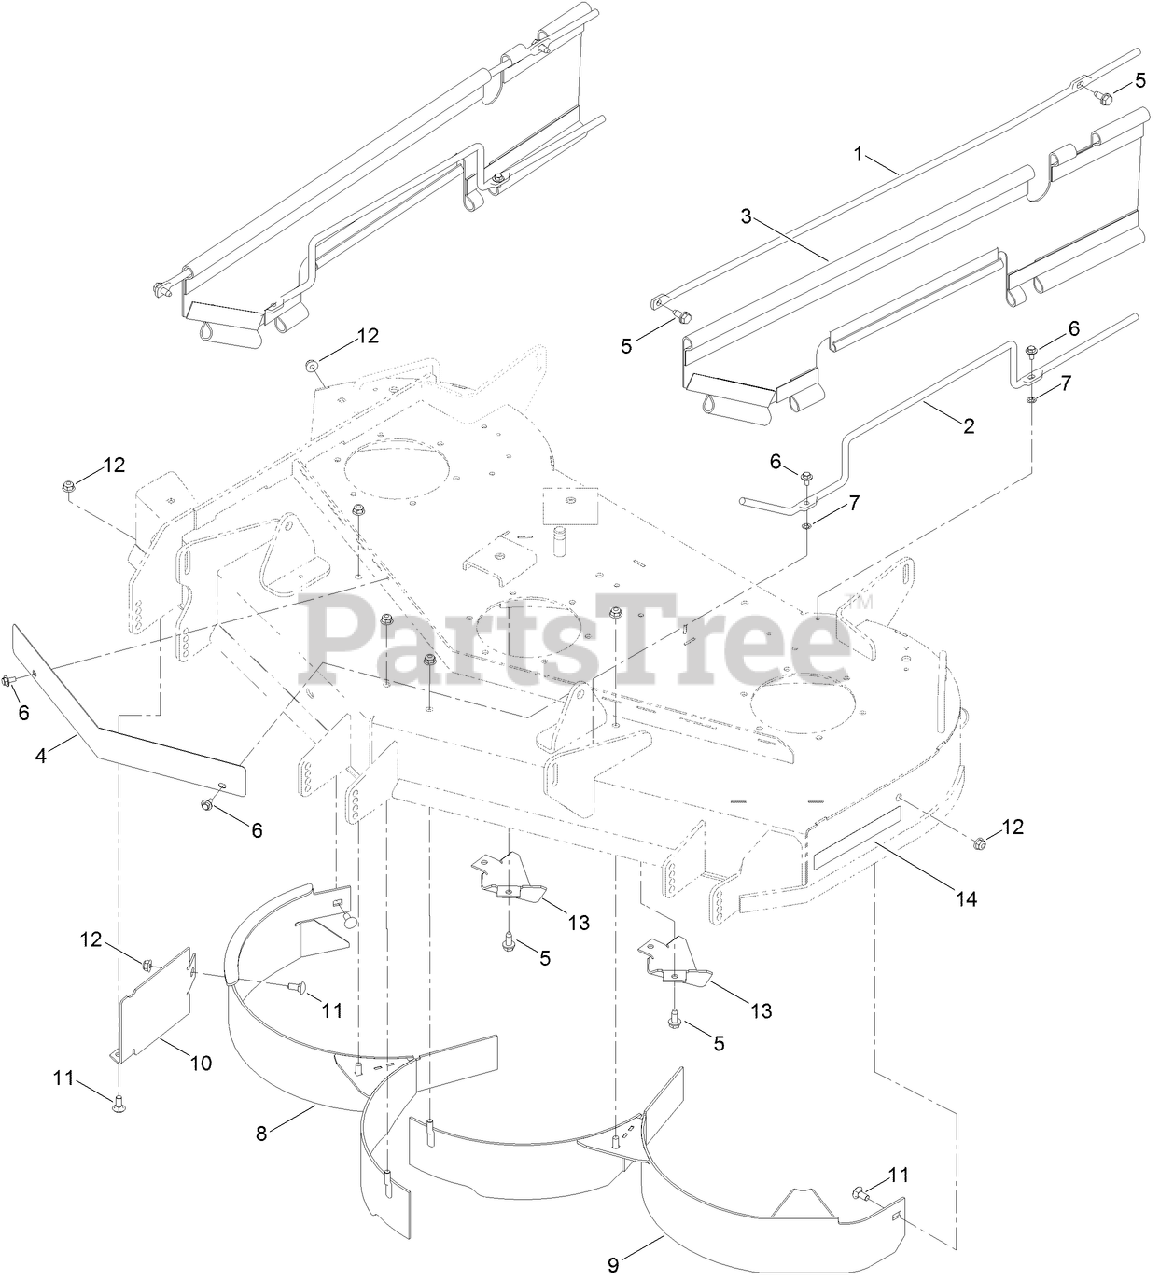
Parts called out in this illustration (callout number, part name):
1	ROD SUPPORT, UPPER
2	ROD SUPPORT, LOWER
3	GUARD-SIDE
4	SHIELD-FRONT
5	SCREW-HWHTF
6	SCREW-HHFTF
7	NUT-RETAINING
8	RH BAFFLE ASM
9	LH BAFFLE ASM
10	GUARD-BAFFLE
11	BOLT-CARR
12	NUT-HF, NI
13	KICKER-FLANGED
14	DECAL-RECYCLER
